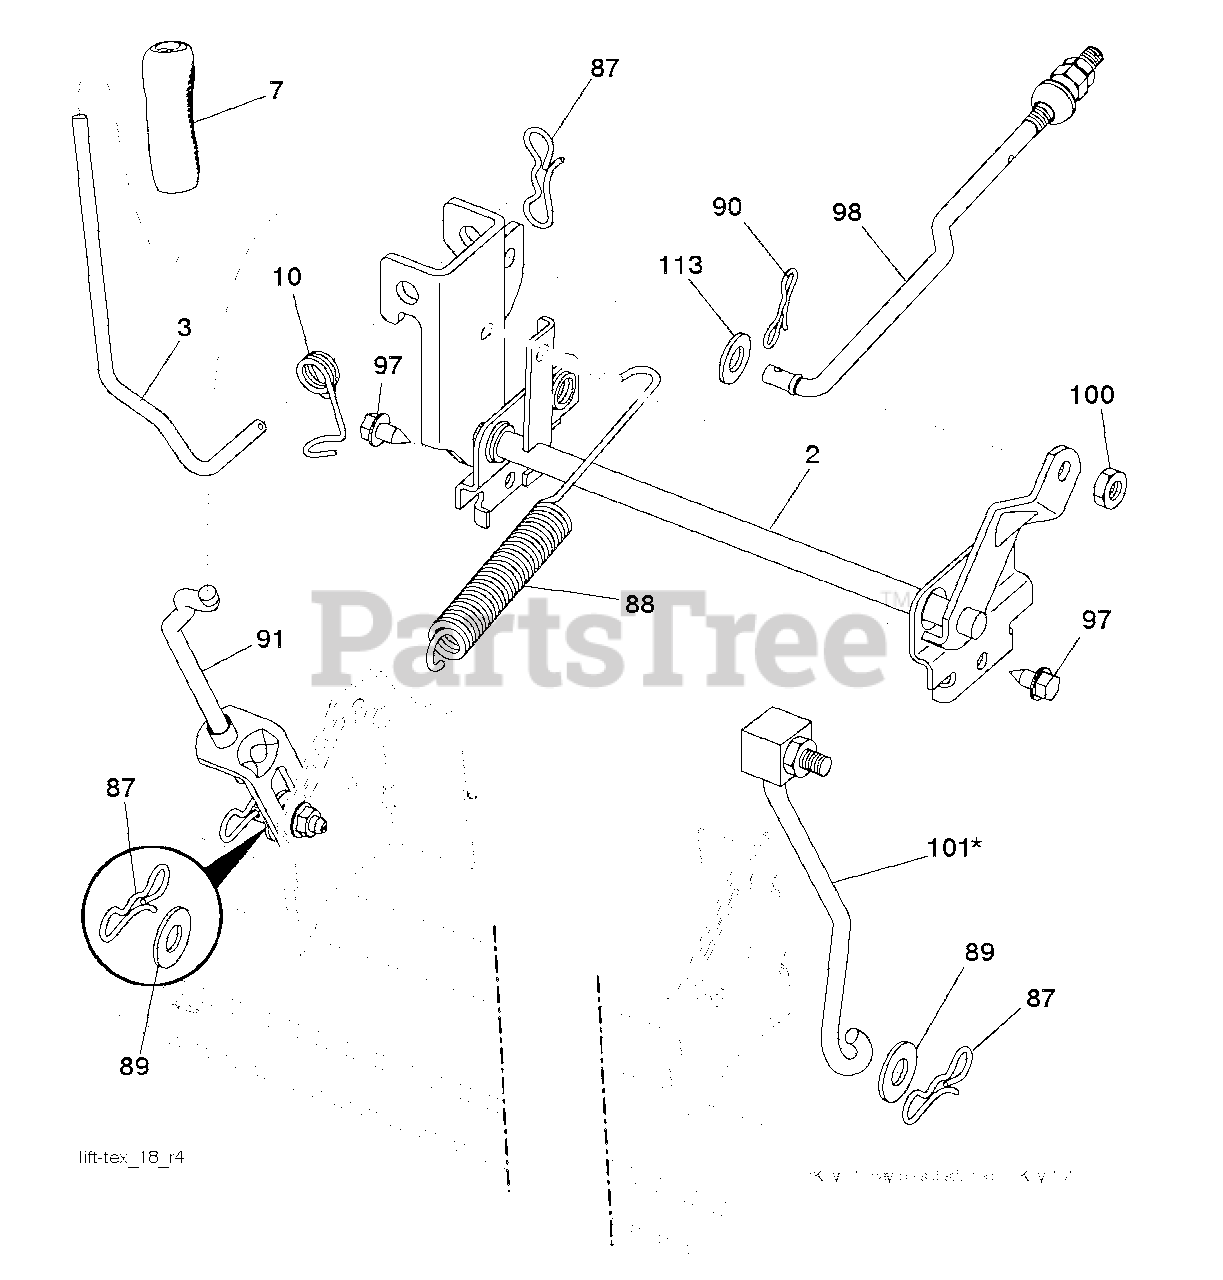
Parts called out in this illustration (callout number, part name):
2	SHAFT.ASM.CROSS.LIFT
3	LEVER.LIFT.HANDLE.LT
7	GRIP.LEVER.
10	SPRING.TORSION.LIFT.HANDLE
87	PIN.COTTER.7/16.BOW TI
88	SPRING.LIFT.ASSIST
89	WASHER.CLEAR.ZINC
90	PIN.COTTER.5/16.BOW TI
91	LINK.ASM.LIFT.REAR
97	SCREW, 3/8-16X3/4
98	LINK.ASM.SUSP.FRONT.MWR.10.5
100	LOCKNUT
101	LINK.ASM.LIFT.FIXE.38/42/46"
